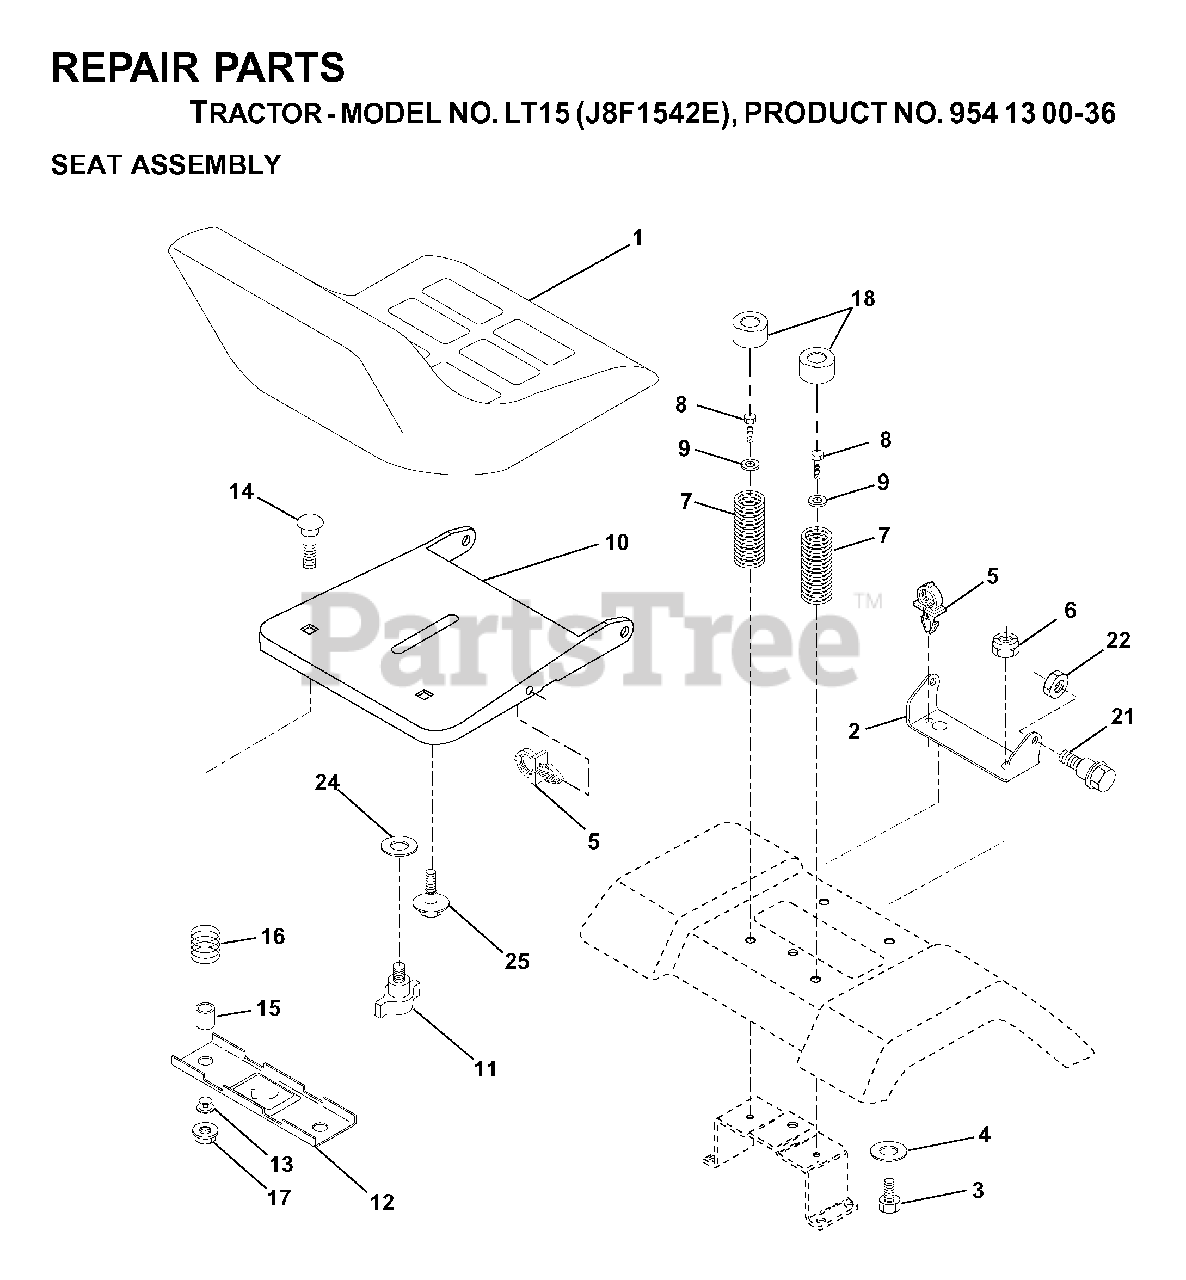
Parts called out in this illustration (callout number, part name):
2	SEAT PIVOT BRKT
4	WASHER PM
5	PUSH CLIP
6	NUT
7	SPRING COMPRESSION
8	SCREW 3/8-16X1
9	WASHER
10	PAN, SEAT
11	KNOB.SEAT.ADJ.WINGNUT
12	BRKT SWITCH
14	BOLT.ROUND.HEAD.SQUARE.NECK
15	SPACER SPLIT 28X.96
17	NUT T
18	CAP SPRING
21	BOLT.SHOULDER.5/16-18
22	NUT.71038.31-18.HEX.NYLOCK
25	BOLT,SHOULD
